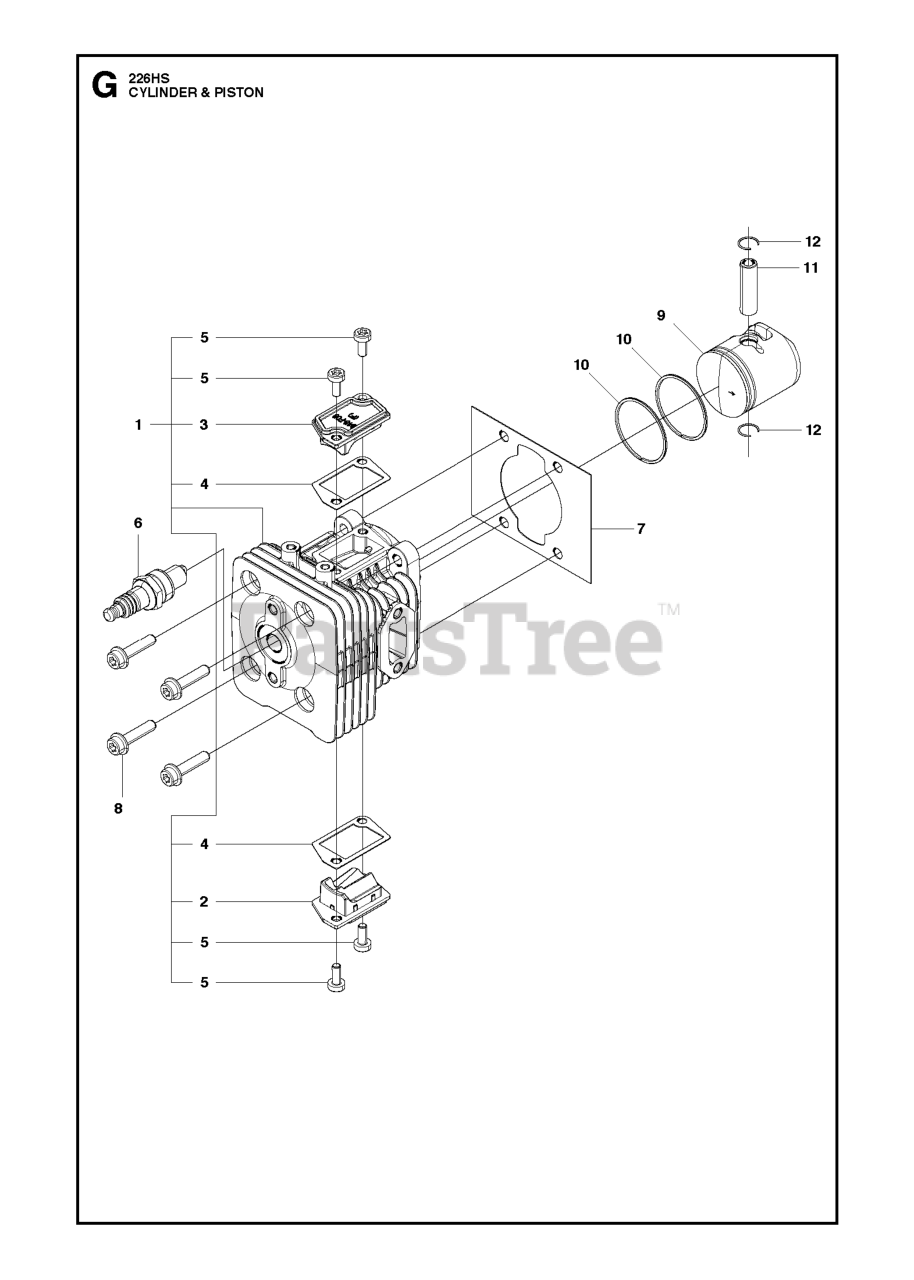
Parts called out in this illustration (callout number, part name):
1	CYLINDER COMP
1	CYLINDER COMPLETE
2	COVER TR(S)
3	COVER TR(F)
4	GASKET, TR
6	SPARK PLUG CMR7H-10
6	PLUG CMR7H
7	GASKET, BASE
9	PISTON
